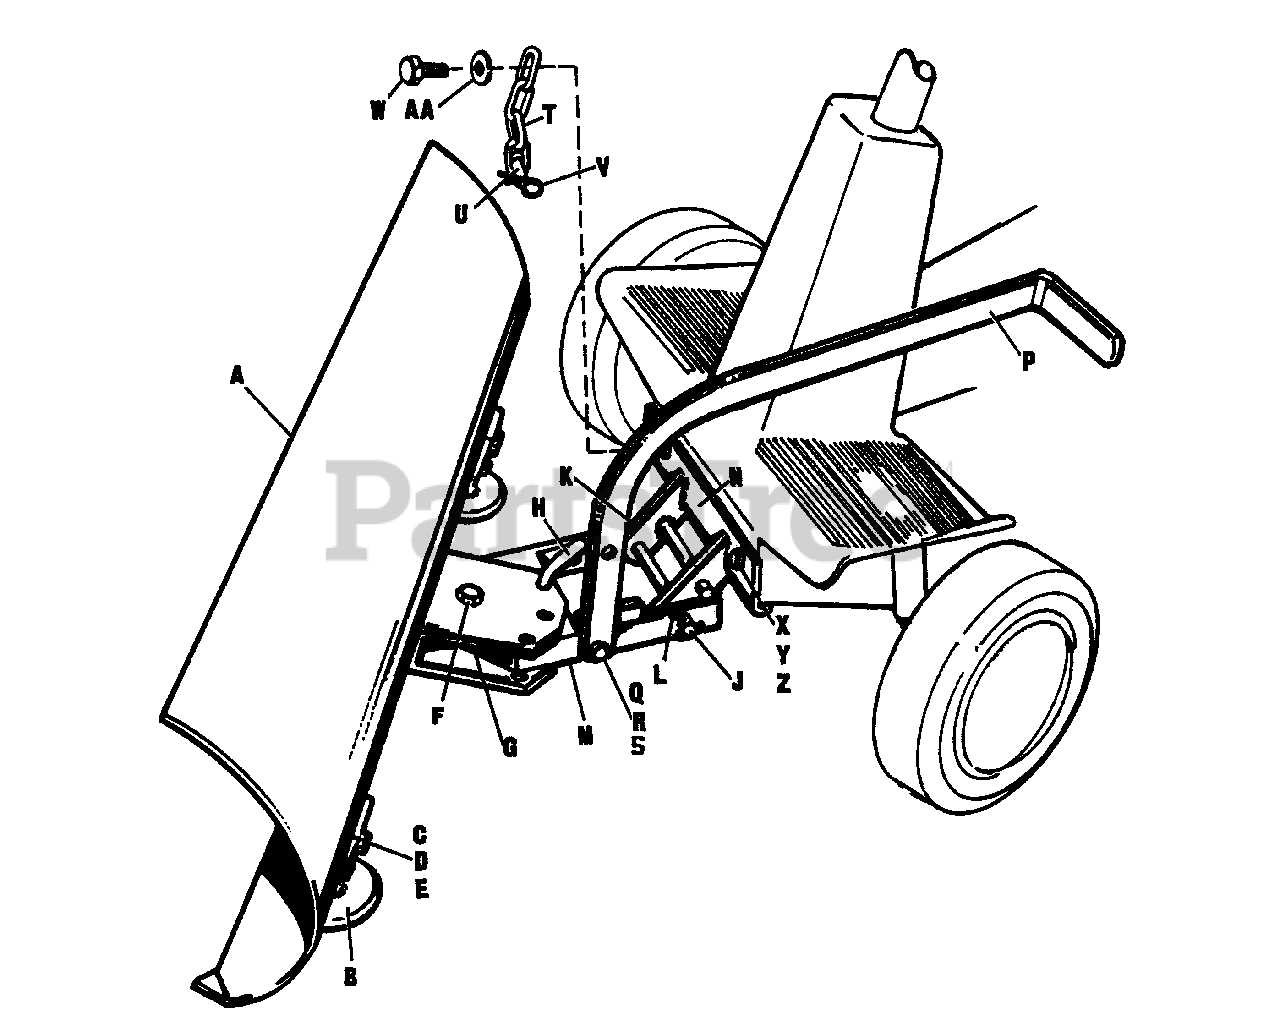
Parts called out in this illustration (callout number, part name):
A	Blade Assembly, 36"
B	Shoe Assembly
C	Carriage Bolt, 3/8-16 x 1
D	Lock Washer, 3/8
E	Hex Nut, Full, 3/8-16
F	Pivot Pin (Vertical)
G	Cotter Pin, 5/32 x 1
J	Pivot Pin, (Horizontal)
K	Spring Clip
L	Cotter Pin, 5/32 x 1
M	Push Bar Assembly
N	Blade Hitch Assembly
P	Foot Lever Assembly
Q	Hex Capscrew, 3/8-16 x 1-1/4
R	Lock Washer, 3/8
S	Hex Nut, Full, 3/8-16
T	Foot Lever Chain
V	Spring Clip
W	Hex Capscrew, 3/8-16 x 1-3/4
X	Lock Washer, 3/8
Y	Hex Nut, Full, 3/8-16
Z	Hex Capscrew, 3/8-16 x 1-1/2
AA	Plain Washer, 3/8
